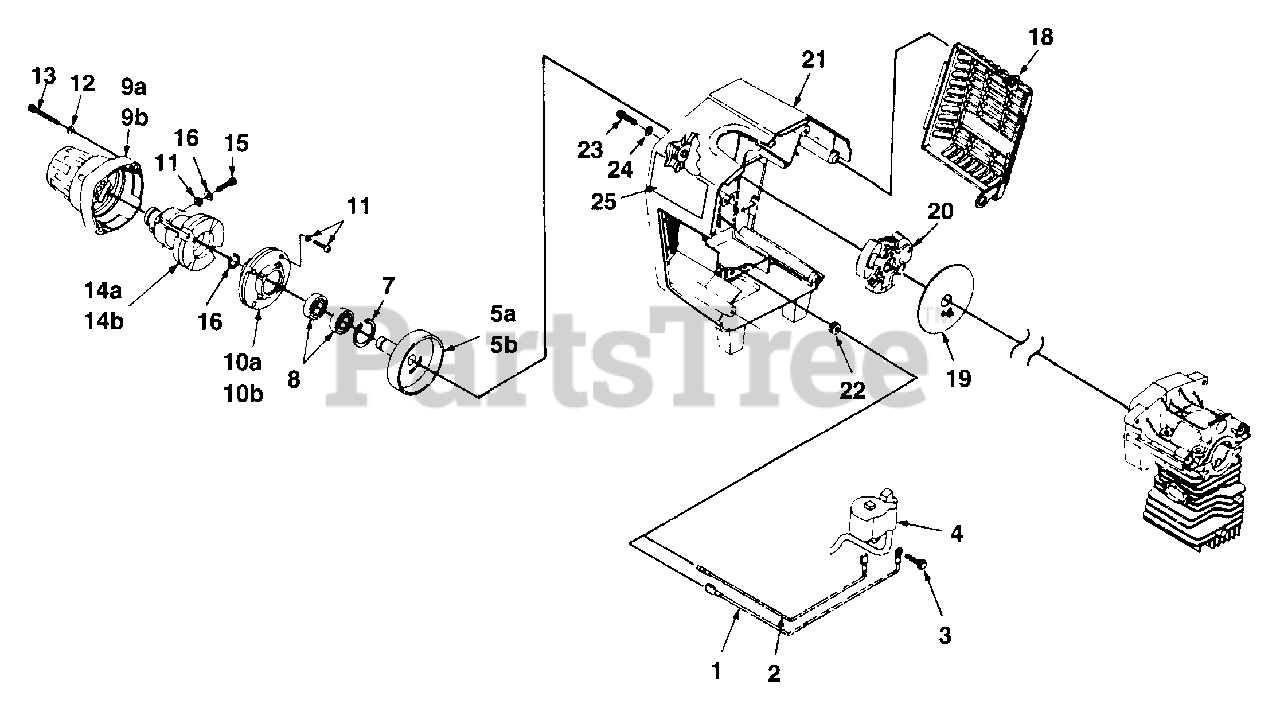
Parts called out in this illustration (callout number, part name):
1	WIRE-Ignition
2	WIRE-Ignition, Ground
3	SCREW-Sems Hex Hd (10-24 X 7/8")
4	MODULE-Ignition (Phelon)
5A	DRUM-Clutch
5B	DRUM-Clutch
7	RING-Snap
8	BEARING-Ball
9A	CASE-Clutch
9B	CASE-Clutch
10A	COVER-Clutch Bearing
10B	COVER-Clutch Bearing
12	WASHER-Flat (#12)
13	SCREW-Socket Hd (12-24 X 1 1/2")
14A	INSERT RING ASSY
14B	INSERT RING ASSY
18	SHIELD-Muffler (Flocked)
19	PLUG-Crankcase
20	CLUTCH
21	SHROUD
22	GROMMET
23	SCREW-Socket Hd (12-24 X 3/4")
24	WASHER-Flat (#12)
25	DECAL-Conformity
